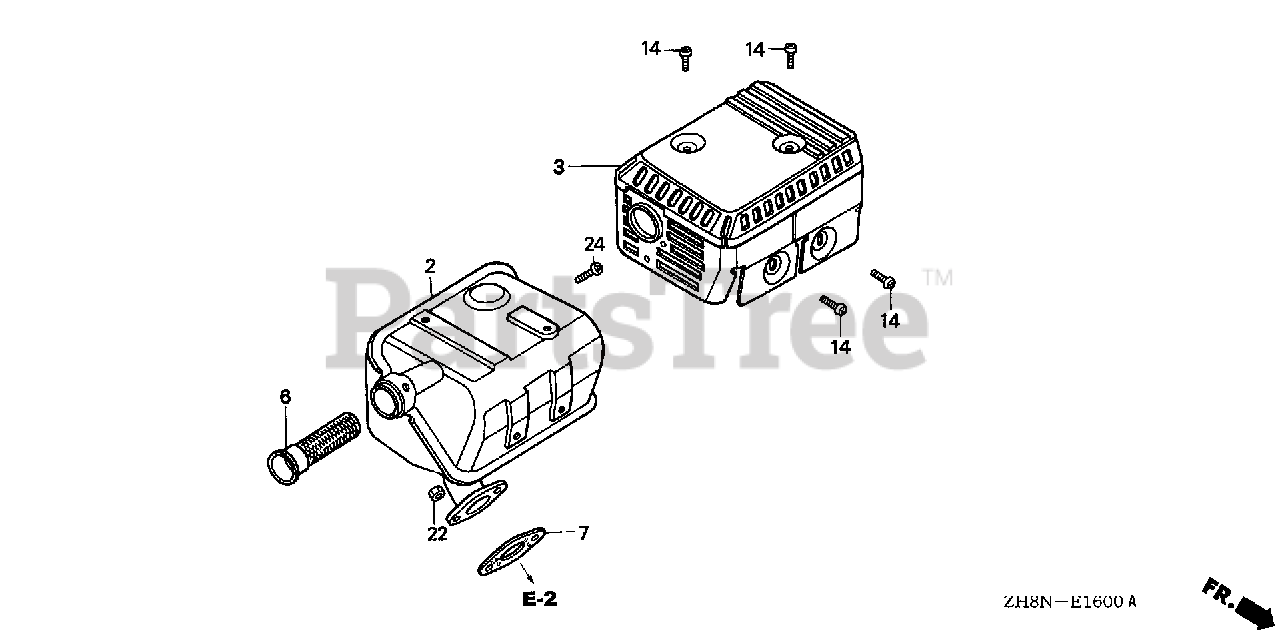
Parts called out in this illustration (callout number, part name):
2	MUFFLER
3	PROTECTOR, MUFFLER
6	ARRESTER, SPARK
7	GASKET, MUFFLER
14	SCREW, TAPPING (5X8)
22	NUT, HEX. (8MM)
24	SCREW, TAPPING (4X6)
